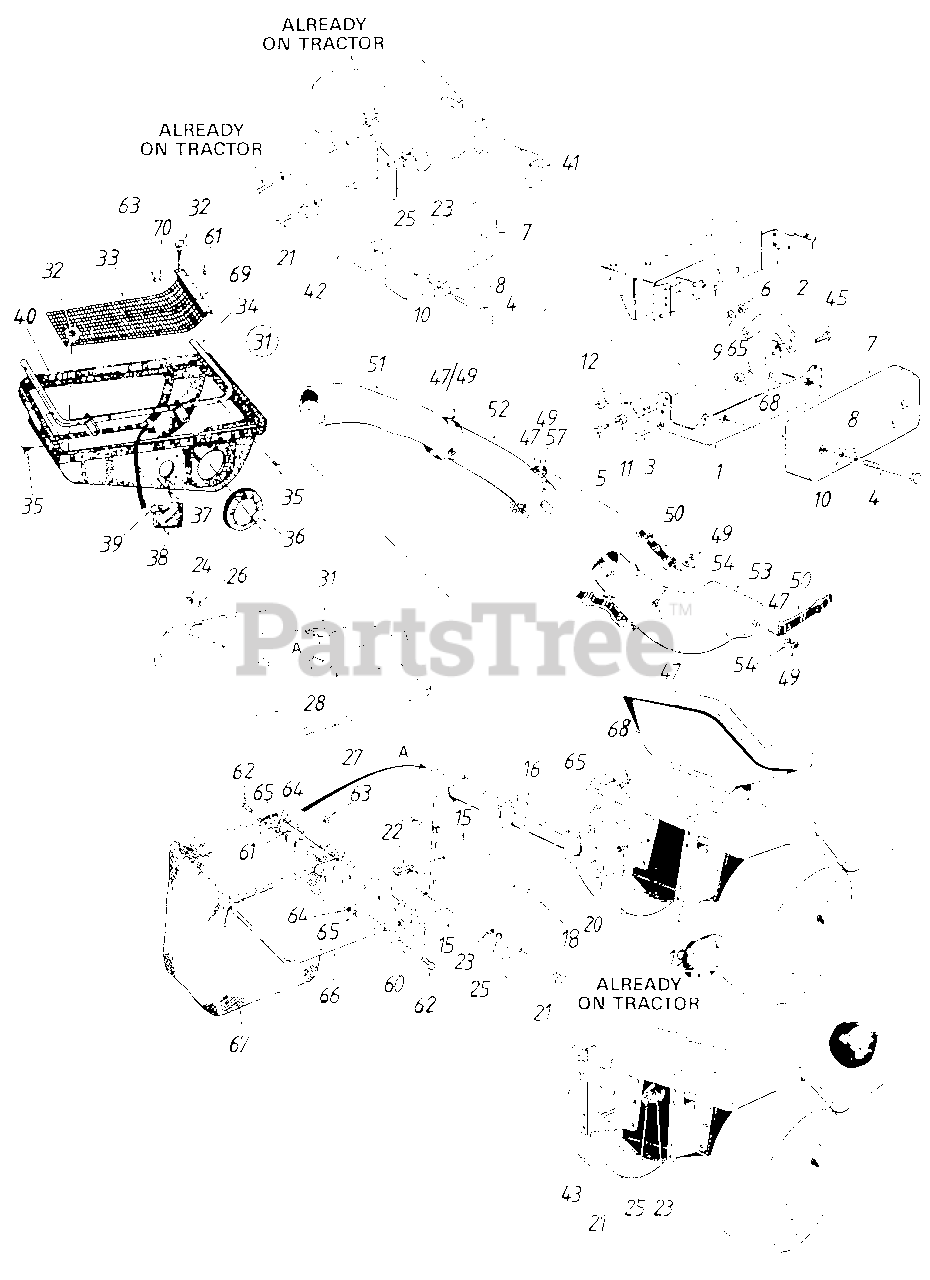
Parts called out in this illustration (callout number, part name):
1	Weight Brkt. Ass'y.
2	Weight Brkt. Tie Strap-L.H.
3	Hex Bolt 7/16-20 x 1.0" Lg.*
4	Hex Bolt 3/8-16 x 4.5" Lg.*
5	Hex AB Tap Scr. 5/16-18 x 1.O"
6	Hex Jam Nut 7/16-20 Thd.
7	Front Counter Weight 38 Ibs.
8	Bell.Wash. 400" I.D. x .88" O.D.
9	L.Wash. 7/16" I.D.
10	Fl.Wash. .390" I.D. x 1.12" O.D.
11	Spacer
12	Weight Brkt. Tie Strap-R.H.
15	Catcher Support Tube Mtg. Brkt
16	Catcher Support Tube Ass'y.
18	Catcher Latch and Support Brkt.
19	Grass Catcher Support Brkt-R.H.
20	Grass Catcher Support Brkt.-LH.
21	Hex Bolt 5/16-18 x .75" Lg.*
22	Hex Bolt 1/4-20 x .62" Lg.-Grade 5
23	Hex Nut 5/16-18 Thd.*
24	Hex Nut 3/8-16 Thd.*
25	L.Wash. 5/16" I.D.*
26	L.Wash. 3/8" I.D.*
27	Shld. Bolt 3/8-16 x .500" Dia.
28	Bell.Wash. .505" I.D. x 1.00" O.D.
31	Grass Catcher Cover Ass'y.
32	Twist Fastener
33	Screen
35	Hex Tap Scr. 1/4-20 x .5" Lg.
36	Seal
37	Truss Mach. B-Tap Scr. #10 x .5" Lg.
38	Plastic Plate
39	Speed Nut
40	Grass Catcher Cover
41	Weight Brkt. Ass'y.-L.H.
42	Weight Brkt. Ass'y.-R.H.
43	Grass Catcher Support Brkt
45	Hex Boit 1/4-20 x .88" Lg.
47	Hex Bolt 1/4-20 x .50" Lg.*
49	Hex Ins. L.Nut 1/4-20 Thd.
50	Retainer Strap Ass'y.
51	Catcher Elbow
52	Catcher Tube
53	Discharge Chute
54	L.Wash. .270" I.D. x .57" O.D.
57	Retainer Hook Brkt.
61	Truss Mach. Scr. #10-24 x .50" Lg.
62	Hex Bolt 1/4-28 x .75" Lg.
63	Hex Sems Nut #10-24 Thd.
64	Hex Nut 1/4-28 Thd.*
65	L.Wash. 1/4" I.D.*
67	Grass Catcher Bag
68	Hex Nut 1/4-20 Thd.*
69	Screen Mtg. Brkt.
70	Flat Wash. 1/4" I.D.
